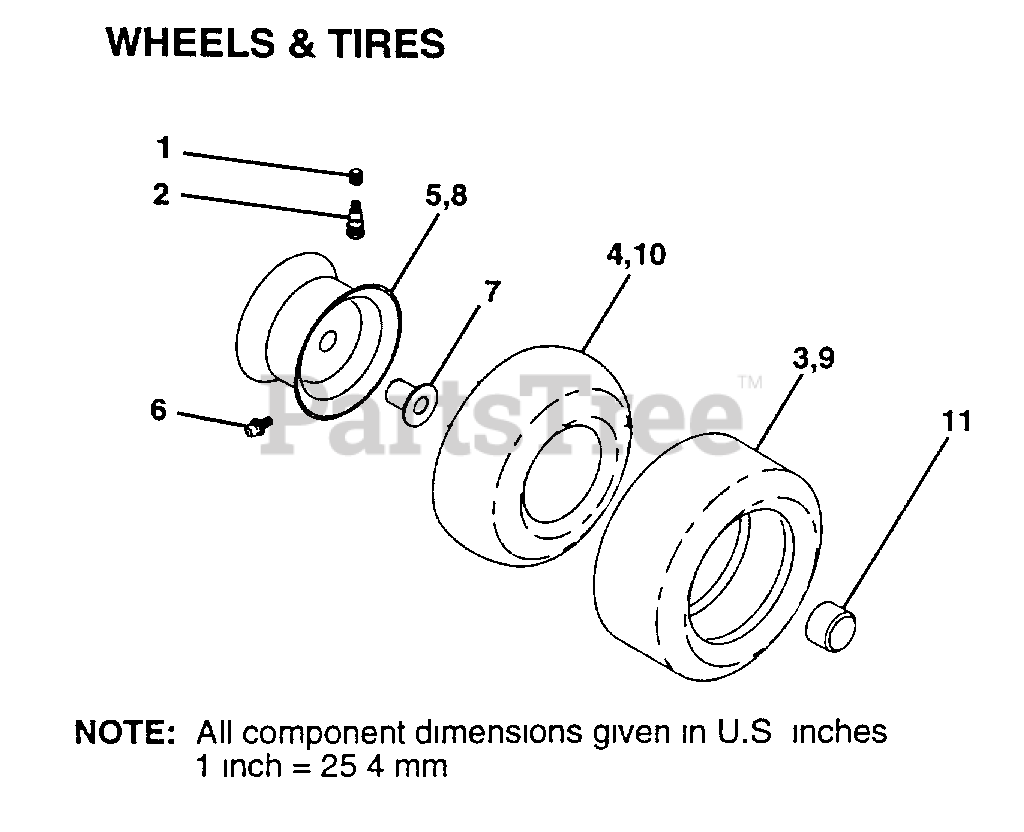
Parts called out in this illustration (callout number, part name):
1	VALVE CAP
2	VALVE STEM LT
4	TUBE.5.3/4.5/6
5	RIM ASM 8" FRONT SILVER SERVICE
6	FITTING LT
7	"FLANGE, BEARING"
8	RIM.REAR.417
10	TUBE.23X8/10-12
11	HUB CAP
